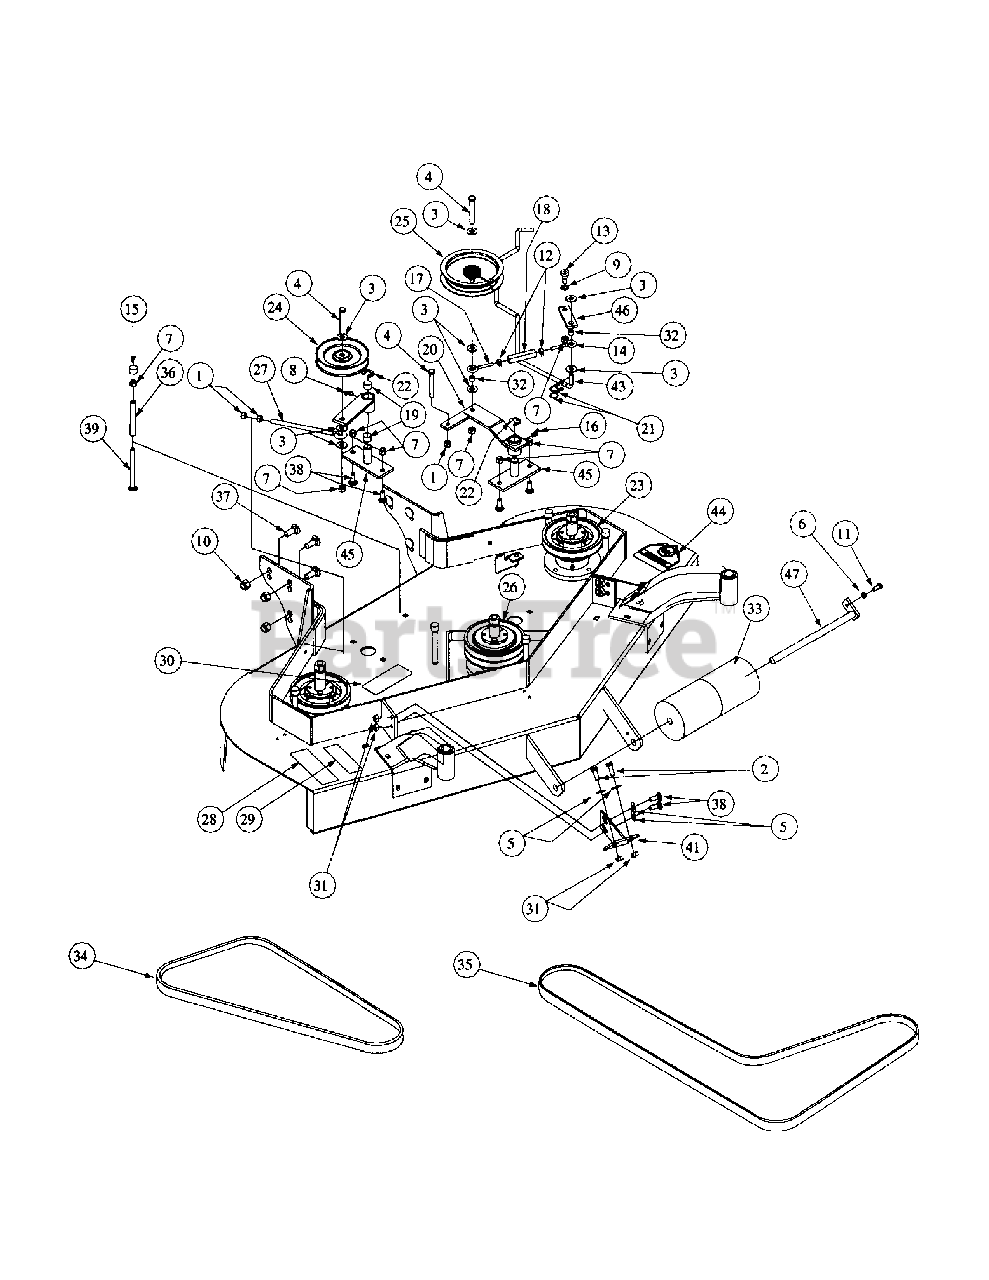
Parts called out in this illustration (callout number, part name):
1	Hex Nut, 3/8-16
2	Hex Cap Screw, 3/8-16, 1
3	Flat Washer, 3/6 Zinc
4	Hex Cap Screw, 3/8-16, 1
5	Flat Washer, 3/8 Zinc
6	Flat Washer, 5/16 Zinc
7	Lock Nut, Nylon Insert, 3/8-16
8	Grease Fitting, 1/4-26, 90°.
9	Shim Washer
10	Lock Nut, Nylon Insert, 1/2-13
11	Hex Cap Screw, 5/16-18 x 3/4
12	Hex Nut, 5/16-18
13	Shoulder Bolt
14	Eye Bolt, Right Hand
15	Vinyl Cap
16	Grease Fitting, 1/4-28 x 3/16
17	Eye Bolt, Left Hand
18	Turnbuckle
19	Idler Arm "B"
20	Idler Arm "A"
21	Hair Pin, 3/8-1/2
22	E-Ring
23	Deck Pulley
24	Idler Pulley
25	Idler Deck Take-up
26	Double Pulley
27	Rob Belt Tensioner
28	Decal Rotating Blade
29	Decal Warning Safety
30	Decal Warning Shield Missing
31	Lock Nut, Metal, 3/8-16
32	Sieve Turnbuckle
33	Roller
34	Drive Belt
35	Drive Belt
36	Spacer Belt Guide
37	Carriage Bolt, 1/2-13 x 1-1/4
38	Carriage Bolt, 3/8-16 x 2
39	Carriage Bolt, 3/8-16 x 4-1/2
40	Mower Deck Weldment, 52"
41	Caster Support Assembly
43	Rod Clutch Link
44	Decal, Danger Hands and Feet
45	Idler Base
46	Clutch Link
47	Axle
